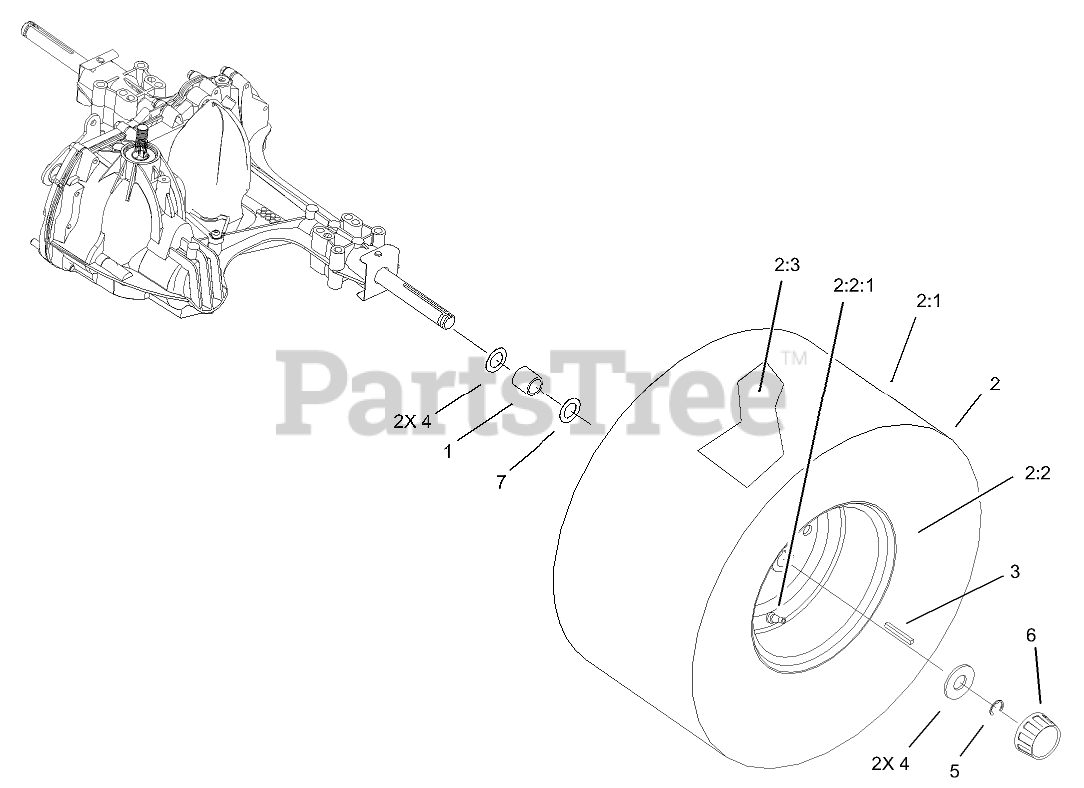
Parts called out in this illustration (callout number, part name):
1	SPACER-WHEEL
2	REAR WHEEL & TIRE ASM
2:2:1	STEM-VALVE
2:3	TUBE-INNER
3	KEY-SQUARE
4	WASHER-PLAIN
5	E-RING
6	CAP-HUB
7	WASHER-THRUST
